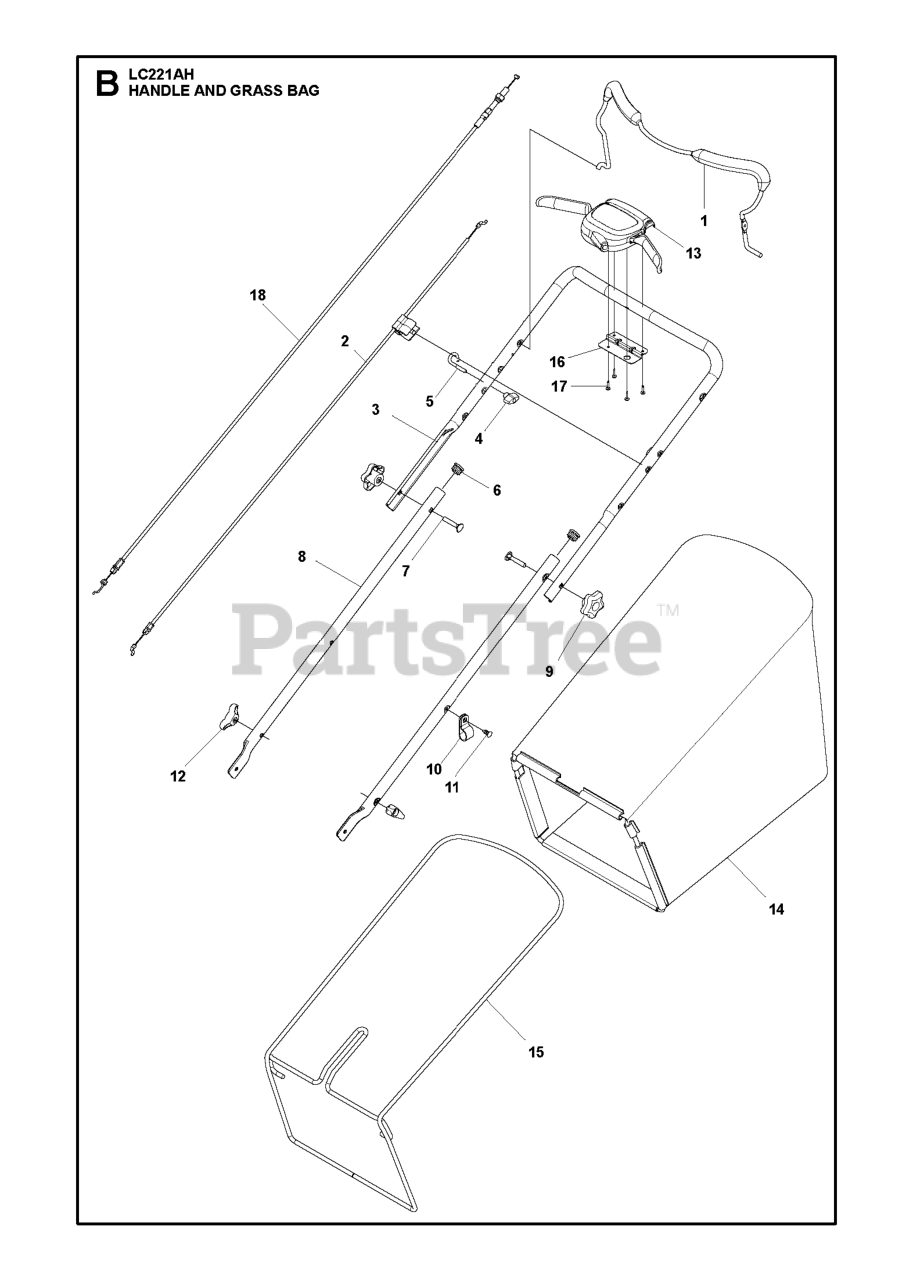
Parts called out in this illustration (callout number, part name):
1	BAIL.OM.ERGO.BENT.MZR.ORAN.668
2	CABLE.MZR.50.SNAP-IN
3	HANDLE.UPPER.3.POS.BS.AW2.GREY
4	T-KNOB.NEW ROPE GUIDE
5	GUIDE.ROPE.BLK.ZINC.CHROM
6	PLUG.PLASTIC.7/8".14-20.GAUGE
7	BOLT.CONCAVE.HEAD.RETAINING
8	HANDLE.LOW.2PC.2POS.21EFF.498
9	KNOB.HANDLE.PLASTIC.STAR.BLACK
10	CLIP.CABLE.BLK
11	FASTENER.PUSH.O.250X0.783
12	KNOB, DEFLECTOR
13	CONTROL.AW2.AW/RG.BS.GY/BK.21E
14	GBAG.C361029EM.HUSQ.GRY.21EFF
15	FRAME.GBAG.AWD.21.BLACK
16	BRACKET DUAL TRIGGER CONTROL
17	SCREW, PHILLIPS HEAD 10 X 5/8
18	CABLE.DRIVE.21EFF.BS.AWD
